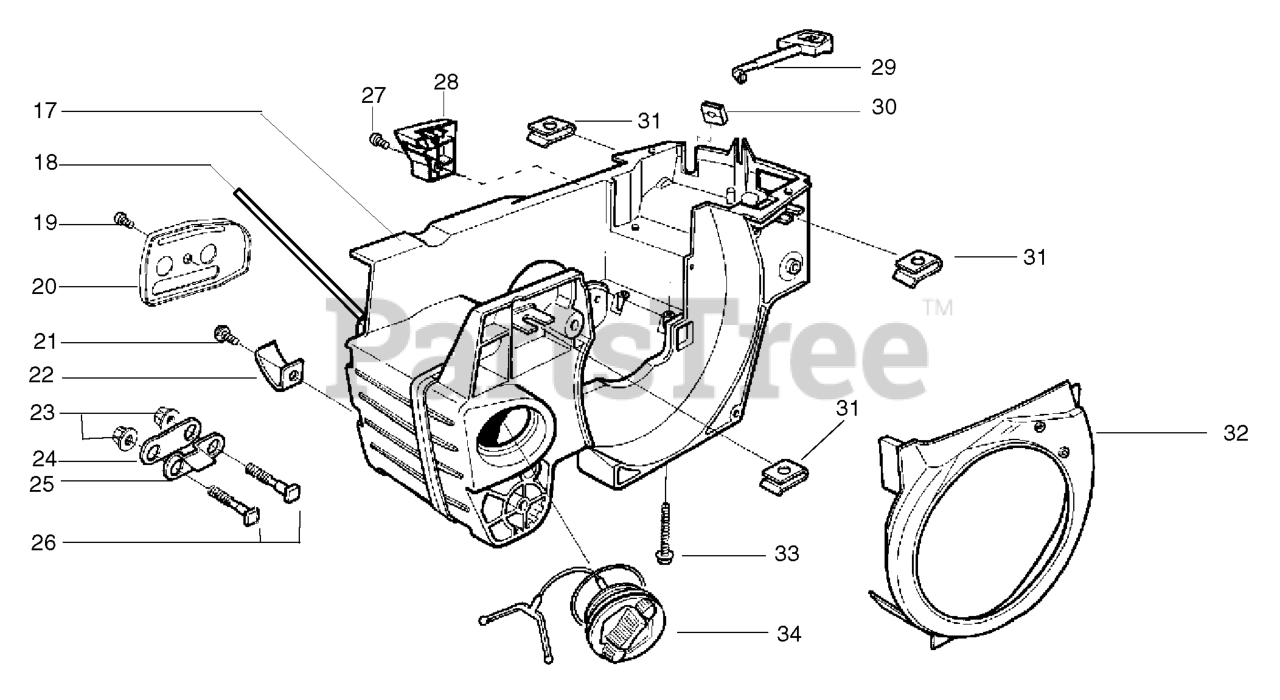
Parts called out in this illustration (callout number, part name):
17	CRANKCASE ASSY
18	TUBE
19	SCREW
22	CHAIN CATCHER 36/41
24	OIL TANK GASKET
25	PLATE,BAR MOUNT
26	BAR BOLT 36/41
28	LIMITER COVER
29	CHOKE 36/41
30	CHOKE GUIDE 36/41
32	AIR CONDUCTOR 36/41
33	SCREW M5-0.8X35M TAP
